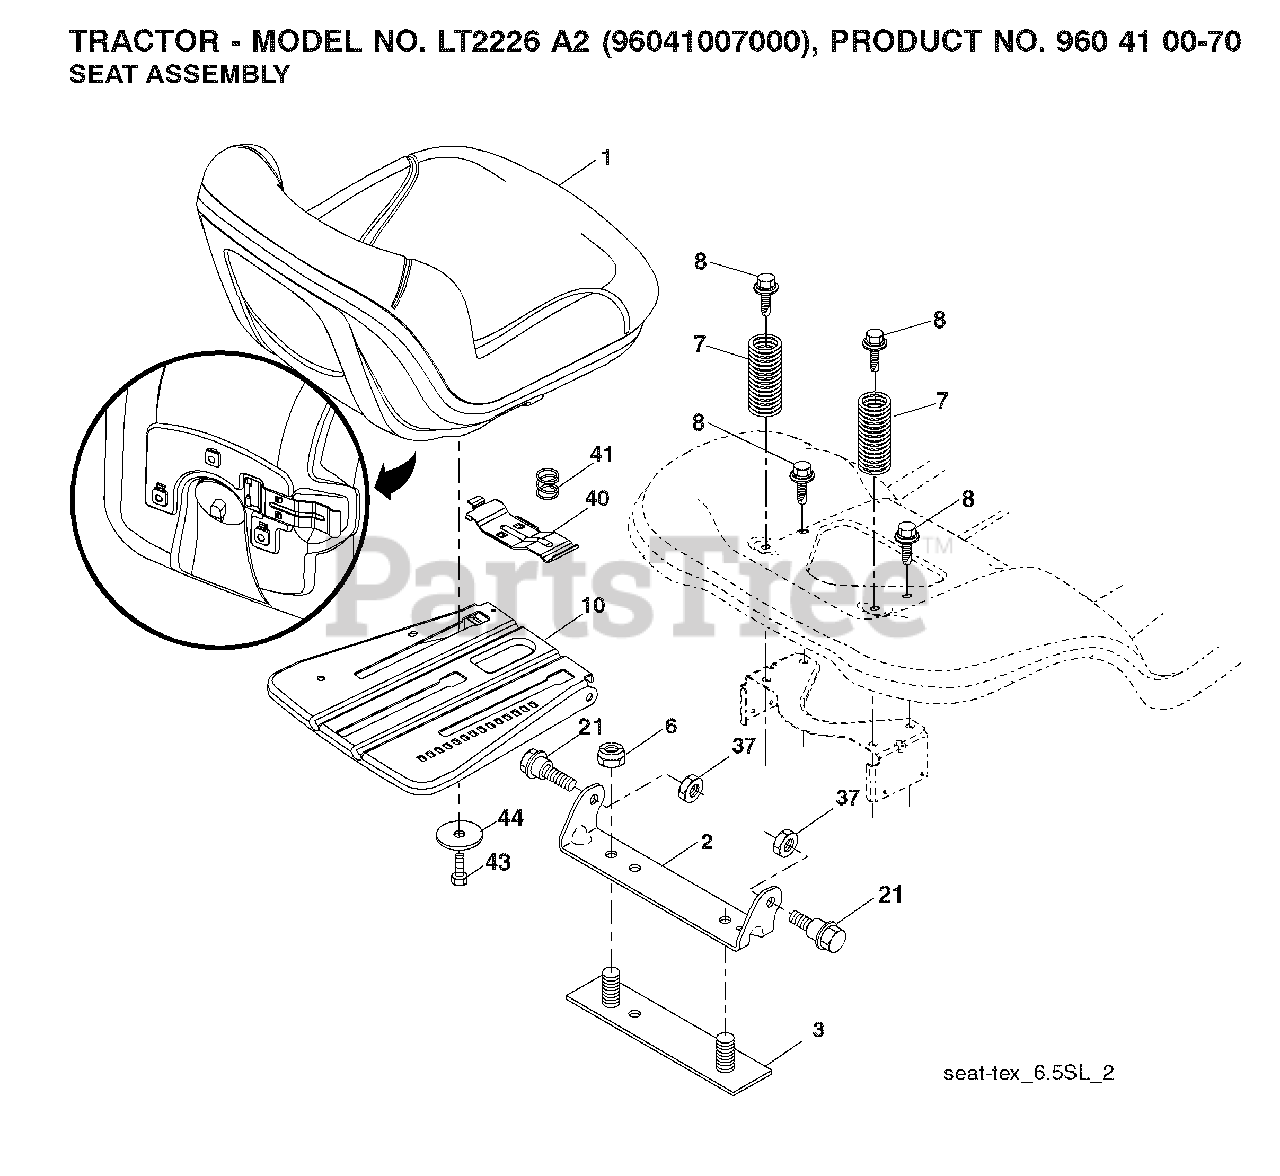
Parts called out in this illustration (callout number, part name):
1	SEAT.TG150.BLK.NLOGO.
2	BRKT.PIVOT.FENDER
6	NUT
7	SPRING COMPRESSION
8	BOLT, 5/16-18 X 1 3/4
10	PAN.ASM.SEAT.3PT
21	BOLT.SHOULDER.5/16-18
37	NUT.71038.31-18.HEX.NYLOCK
40	HANDLE.SLIDE.SEAT.TEX.BLACK
41	SPRING.LATCH.SEAT.TEX
44	WASHER 13/32 X 2-3/8 X 12GA
